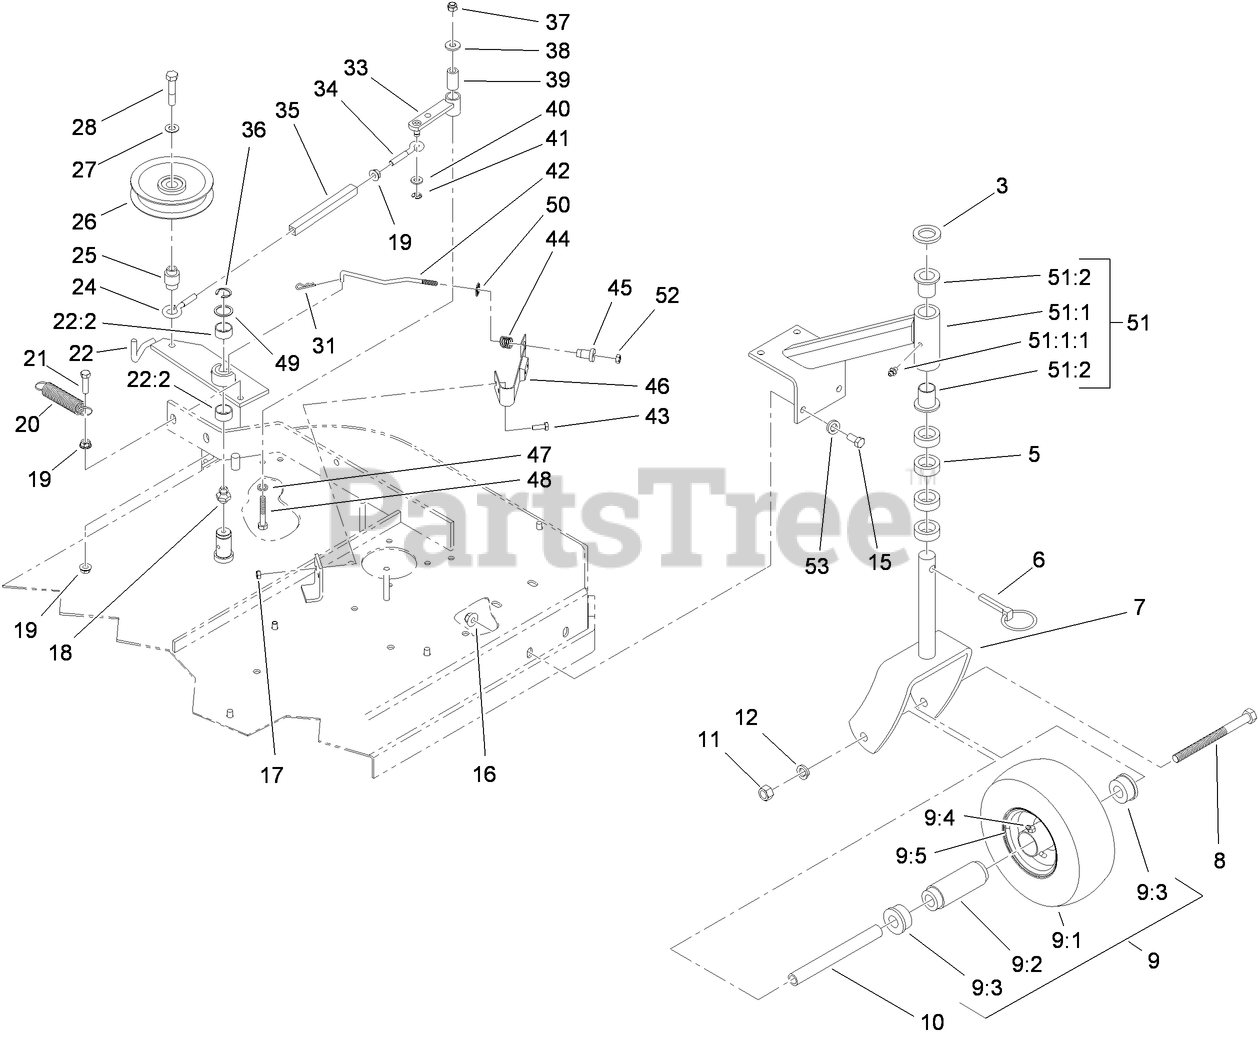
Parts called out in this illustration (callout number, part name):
3	WASHER-FLAT
5	SPACER-CASTER
7	FORK
8	SCREW-HH
9	WHEEL AND TIRE ASM
9:1	TIRE
9:2	BEARING
9:3	BUSHING
9:4	FITTING-GREASE
9:5	WHEEL
10	SPACER
11	NUT-HH
12	WASHER-LOCK
15	SCREW-HH
16	NUT-HF, NI
17	NUT-LOCK, NI
18	FITTING-GREASE
19	NUT-HF
20	SPRING-EXTENSION
21	SCREW-HH, SPECIAL
22	Idler Arm ASM
22:2	SLEEVE-BEARING
24	EYEBOLT-THREAD, LH
25	BUSHING-ENGAGEMENT
26	PULLEY-IDLER
27	WASHER-BELLEVILLE
28	SCREW-HH
31	PIN-COTTER
33	ARM-ASSIST
34	EYEBOLT-THREAD, RH
35	BODY-TURNBUCKLE
36	RING-RETAINING, EXT
37	NUT-LOCK, NI
38	WASHER-FLAT
39	TUBE-PIVOT
40	WASHER-PLAIN
41	RING-RETAINING, EXT
42	Rod-Brake
43	SCREW-HH
44	SPRING-COMPRESSION
45	SPACER-FLANGED
46	PAD AND SPRING ASM
47	WASHER-SPRING
48	SCREW-HH
49	WASHER-SPINDLE
50	RING-PUSH ON
51	SUPPORT ASM
51:1	Support-Caster
51:1:1	FITTING-GREASE
51:2	BEARING-FLANGED
52	NUT-LOCK, NI
53	WASHER-FLAT
